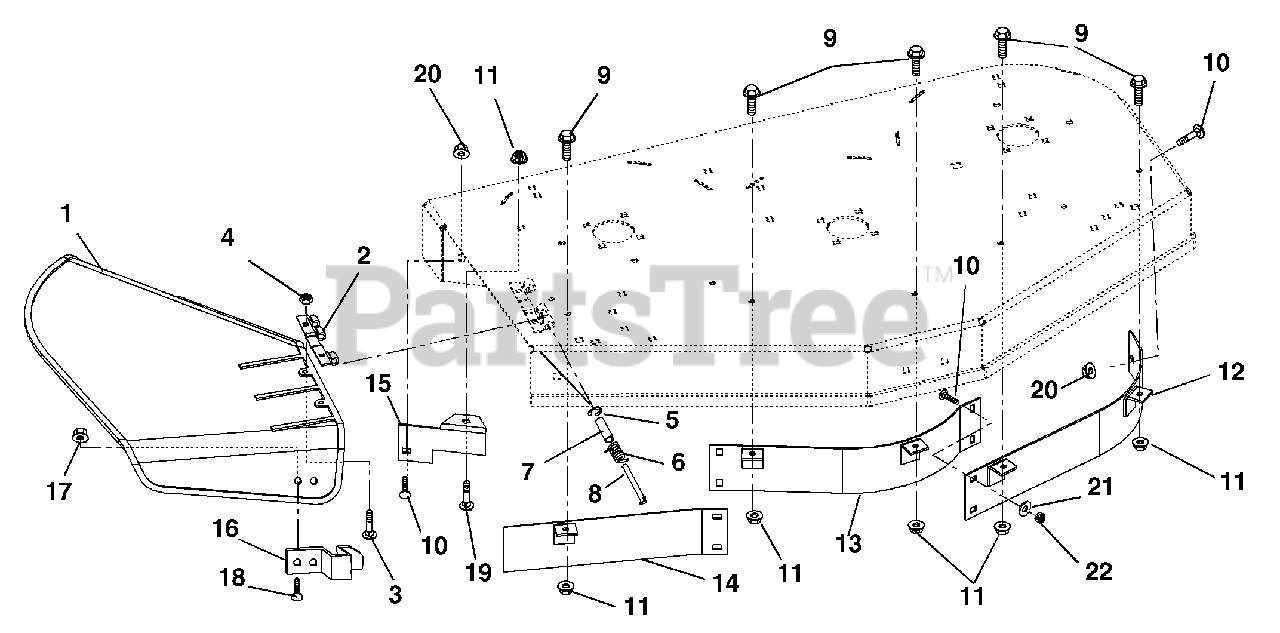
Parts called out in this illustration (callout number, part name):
1	Deflector, Chute
2	Hinge, Plate
3	Bolt, Round Head Square Neck .25-20 x .75 Grade 5
4	Nut-Locking-Flange .250-20
5	Ring, Retaining External .312 x .025
6	Spring, Torsion .095 x .50 x 1.00
7	Bushing, Sleeve
9	Bolt, Serrated Hex Flange Washer Head .31-18 x .62
10	Bolt, Round Head Square Neck .31-18 x .62
11	Nut-5/16-18 Flange Nyloc
12	Weldment, Upper Left Baffle-40" (044)
12	Weldment, Upper Left Baffle-44" (046)
12	Weldment, Upper Left Baffle-48" (048)
12	Weldment, Upper Left Baffle-52" (050)
13	Weldment, Upper Center Baffle-40" (044)
13	Weldment, Upper Center Baffle-44" (046)
13	Weldment, Upper Center Baffle-48" (048)
13	Weldment, Upper Center Baffle-52" (050)
14	Weldment, Upper Right Baffle-40" (044)
14	Weldment, Upper Right Baffle-44" (046)
14	Weldment, Upper Right Baffle-48" (048)
14	Weldment, Upper Right Baffle-52" (050)
15	Deflector, 40" (044)
15	Deflector, 44"/48" (046, 048)
15	Deflector, 52" (050)
16	Flat Spring
17	Nut, Locking Top Flange .25-20
18	Bolt, Round Head Square Neck .25-20 x .50 Grade 5
19	Bolt, Round Head Square Neck .38-16 x .75 Grade 5
20	Nut 5/16-18 Flange Nyloc
21	Washer, Flat Steel .344 x .688 x .065
22	Nut, Locking Nylon .312-18
